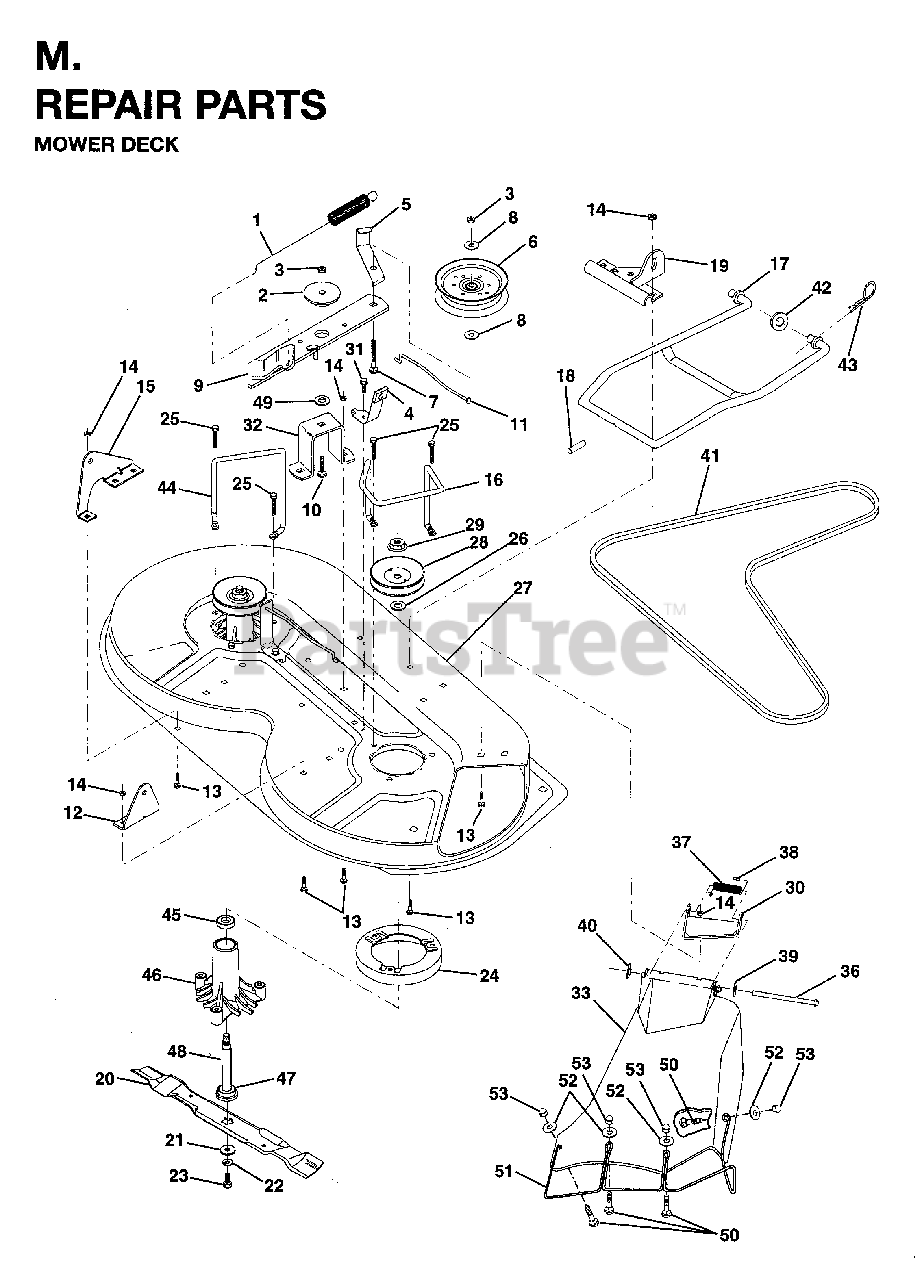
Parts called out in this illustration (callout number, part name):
1	SPRING-MOWER CLUTCH
2	SPACER RETAINER
3	LOCKNUT
4	BRAKE ASSEMBLY
5	IDLER BELT GUIDE
6	PULLEY IDLER
7	BOLT
8	WASHER
9	IDLER ARM ASSY
10	BOLT.3/8-14X1.25
11	BRAKE ROD
12	BRKT LIFT REAR
13	BOLT
14	LOCKNUT
15	BRKT LIFT REAR LH
16	KEEPER RH
17	MOWER LINK STABILIZER
18	PIN GROOVE
19	BRKT LINK STABILIIZER
20	BLADE, HI-LIFT 36" PREMIUM
21	WASHER.BLADE
22	WASHER, LOCK 3/8
23	BLADE BOLT
24	STRIPPER
25	SCREW
26	WASHER
27	MOWER HOUSING
28	PULLEY
29	NUT
30	BRACKET ASM DEFLECTOR
32	SUPT,IDLER ARM
33	DEFLECTOR
36	HINGE ROD
37	SPRING TORSION
38	CAP-SLEEVE LT
39	WASHER - 15X7.3X1.6
40	NUT PUSH M
42	WASHER - M12
43	SPRING RETAINER
44	KEEPER LH
46	HSG MANDREL
47	BEARING
48	SHAFT ASM VENT
49	HARDENED WASHER
50	SCREW
53	NUT
